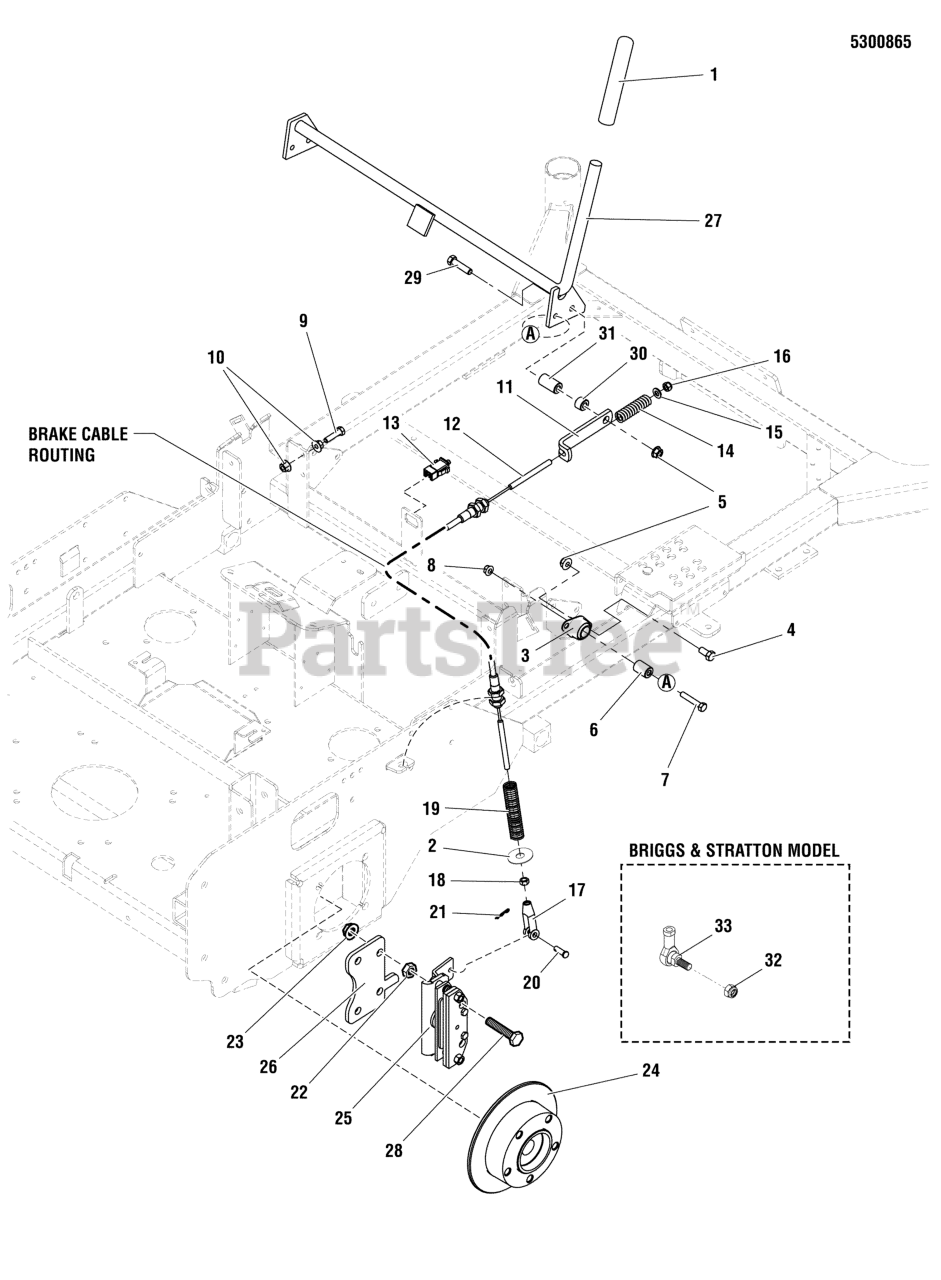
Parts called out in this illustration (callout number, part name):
1	GRIP, FOAM, 3/4 ID X 6 X .187
2	WASHER, 5/16" FENDER
3	BEARING, BRONZE FLANGE, 3/4
4	BOLT, 3/8-16 X 3/4" GD5 CZ
5	NUT, 3/8-16 HEX NYLOCK FLANGE
6	SPACER, .32 X .75 X 1.06
7	BOLT, 5/16-18 X 1-3/4 GD5 YZ
8	NUT, 5/16-18 HEX NYLOCK FLANGE
9	BOLT, 5/16-18 X 1-1/4 GD5 YZ
10	NUT, 5/16-18 HEX SERRATED FLANGE (LARGE)
11	LINK, BRAKE LOCK - BLK
12	CABLE, PARKING BRAKE
13	SWITCH, DP NO/NC SNAP-IN
14	SPRING-COMP, .75 X .162 X 2.5
15	WASHER, 5/16" SAE
16	NUT, 5/16-24 HEX NYLON LOCK
17	CLEVIS, 5/16-24, PLASTIC
18	NUT, 5/16-24 HEX
19	SPRING, COMPRESSION, 5-1/2"
20	PIN, CLEVIS, 5/16 X 1 YZ
21	PIN, HAIR, .0585 X 1-1/8, 1/4 EYE, YZ
22	NUT, 1/2-13 HEX JAM
23	NUT, 1/2-13 HEX NYLON LOCK
24	WHEEL HUB, COMPACT CALIPER (86720)
25	COMPACT CALIPER, AUSCO (86978)
26	MOUNT, BRAKE CALIPER - RED
27	WELD, BRAKE SHAFT - RED
28	BOLT, 1/2-13 X 4" GD5 CZ
29	BOLT, 3/8-16 X 2, GD5, CZ
30	SPACER, .38 X .50 X .27
31	SPACER, .390 X 1.00 X 1.00 - YZ
32	NUT, 5/16-24 HEX
33	BALL JOINT 5/16-24 LH FEMALE W/STUD, BR
